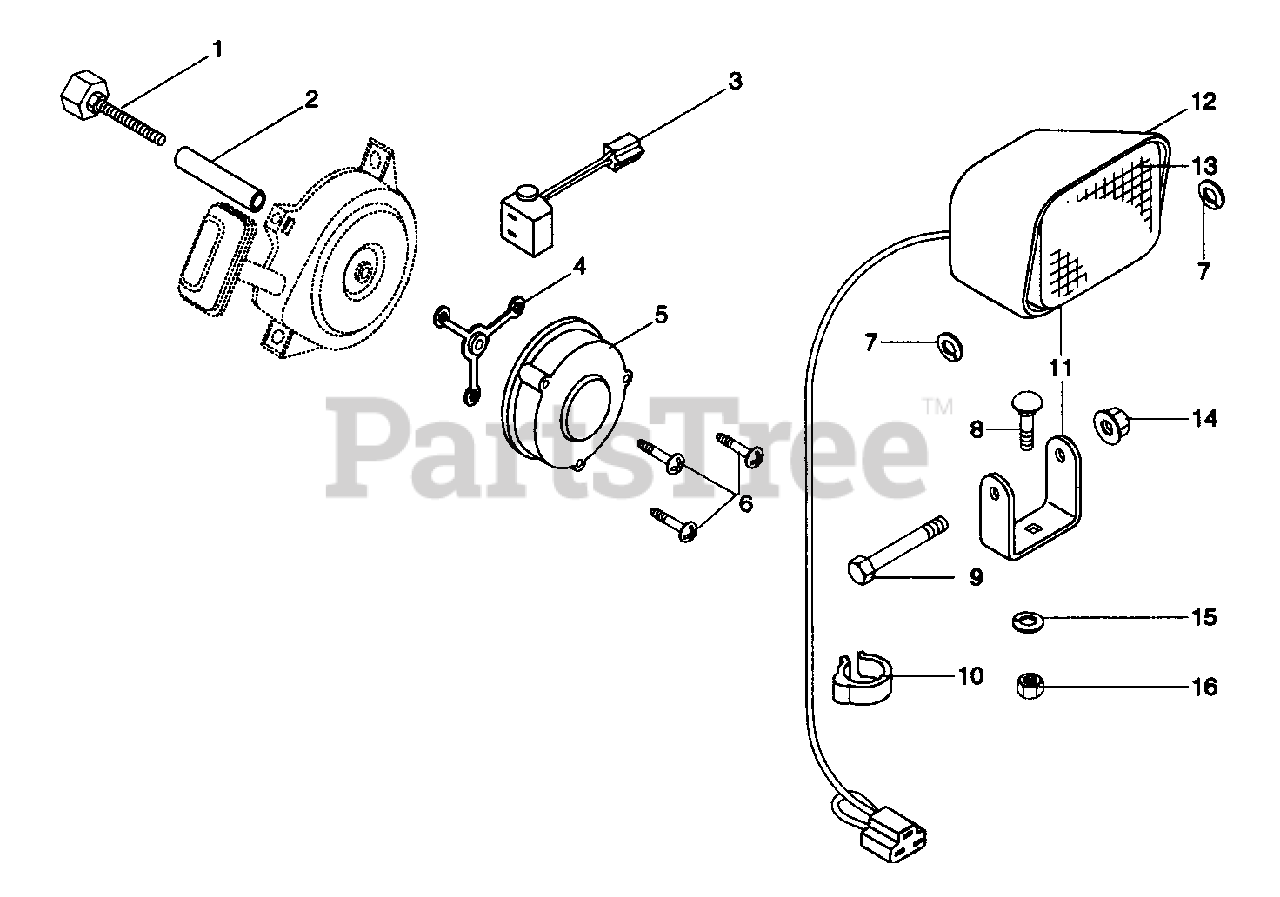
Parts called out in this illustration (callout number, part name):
1	ALTERNATOR SHAFT 3.00
1	ALTERNATOR SHAFT-3.55
2	CENTERING TUBE
3	LIGHTING CONNECTOR
4	SPACER-ALTERNATOR
5	ALTERNATOR
6	SCR-TAP 8-18X1.25 CRFH PL B
7	WSHR-LK-EXT .313X.030 PL
8	BLT-RDHDSQNK .31-18X1.00 PL
8	BLT-HEX .31-18X2.50 PL GR2
10	CLAMP
11	HEADLIGHT
12	LENSE-FLOOD
13	BULB
14	NUT-FLG. .312-18 PL
15	WSHR-LK .312X.097 PL HVY
16	NUT-HEX .312-18
